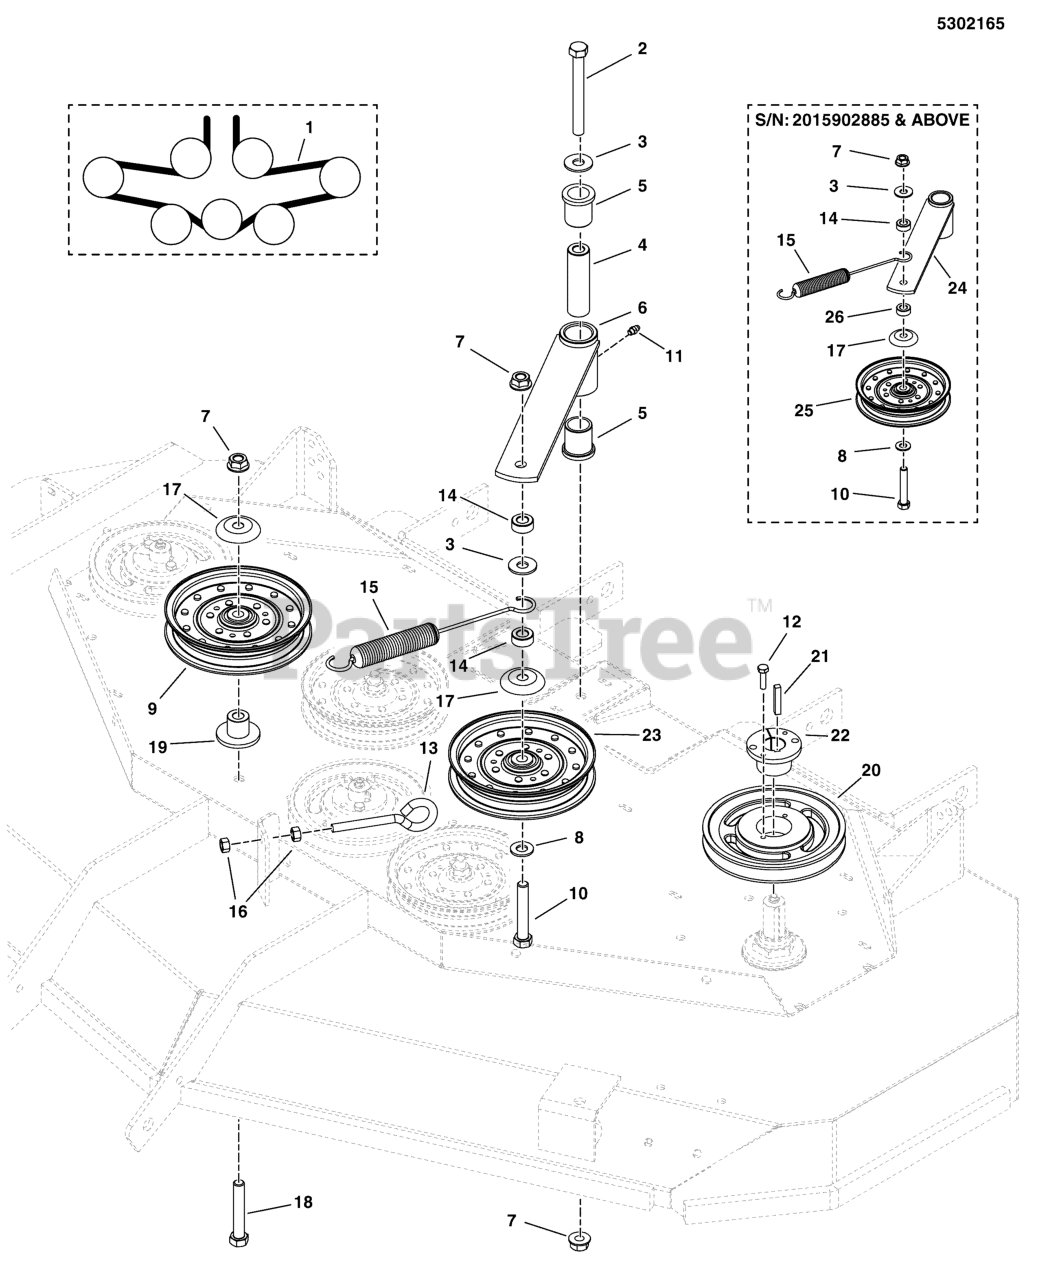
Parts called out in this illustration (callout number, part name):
1	BELT, 5V, 197.90"EL, LRG ARAMID, WRP, RC
2	BOLT, 1/2-13 X 4-1/2 GD5 YZ
3	WASHER, 1/2 USS
4	SPACER, .52 X 1.00 X 3.50
5	BUSHING, FLANGE
6	IDLER ARM ASSEMBLY
7	NUT, Hex Flange, Nylock, 1/2-13
8	WASHER, 1/2 SAE
10	BOLT, 1/2-13 X 3" GD5 CZ
11	GREASE FITTING, 1/4-28, 90 DEGREE
12	BOLT, 1/4-20 X 1" GD5 CZ
13	EYE BOLT, 3/8-16 X 5, 2.88THRD, 1EYE, CZ
14	SPACER, .52 X 1.00 X .44, CZ
15	SPRING-EXT, 1.04 ODX10.535LGX.148WR, BLK
16	NUT, 3/8-16 HEX
17	SHIELD, PULLEY BEARING
18	BOLT, 1/2-13 X 3-1/2, HEX HD, GD5, CZ (SV)
19	IDLER MOUNT
20	PULLEY, SPINDLE, BH66
21	KEY 1/4 SQ X 1 1/2 LONG
22	BUSHING, TAPERED HUB
24	IDLER ARM ASSEMBLY
26	SPACER, .52 X 1.00 X .63, CZ
